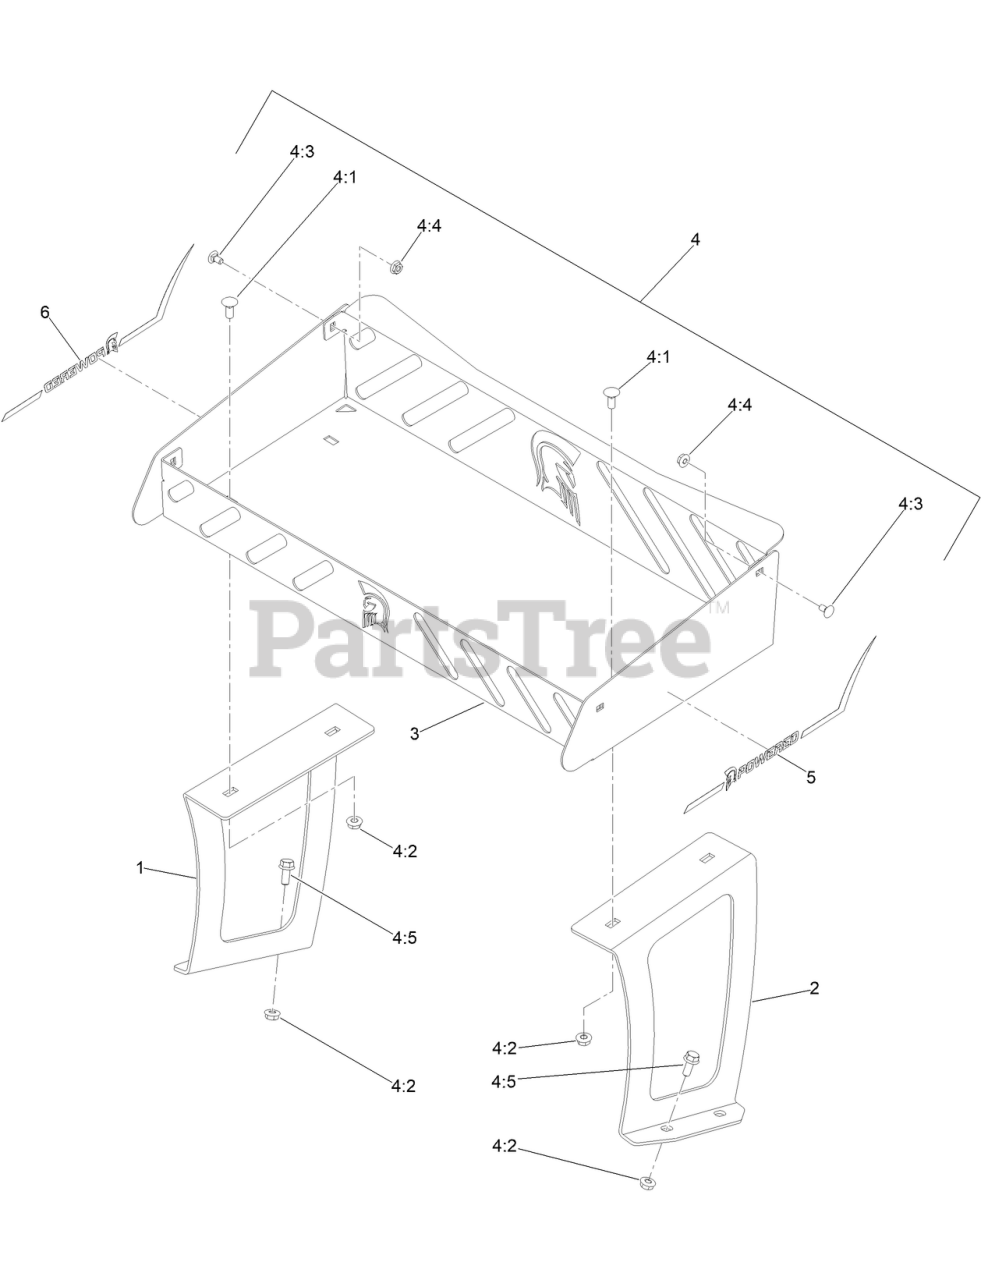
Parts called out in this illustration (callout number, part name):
1	SPOILER BASKET UPRIGHT
2	SPOILER BASKET UPRIGHT
3	REAR BASKET
4	SPOILER HARDWARE KIT
4:1	BOLT-CARR
4:3	SCREW-CARR
4:4	1/4-20 HEX FLANGE NUT
4:5	SCREW-HHF
5	DECAL-POWERED WING
6	DECAL-POWERED WING
